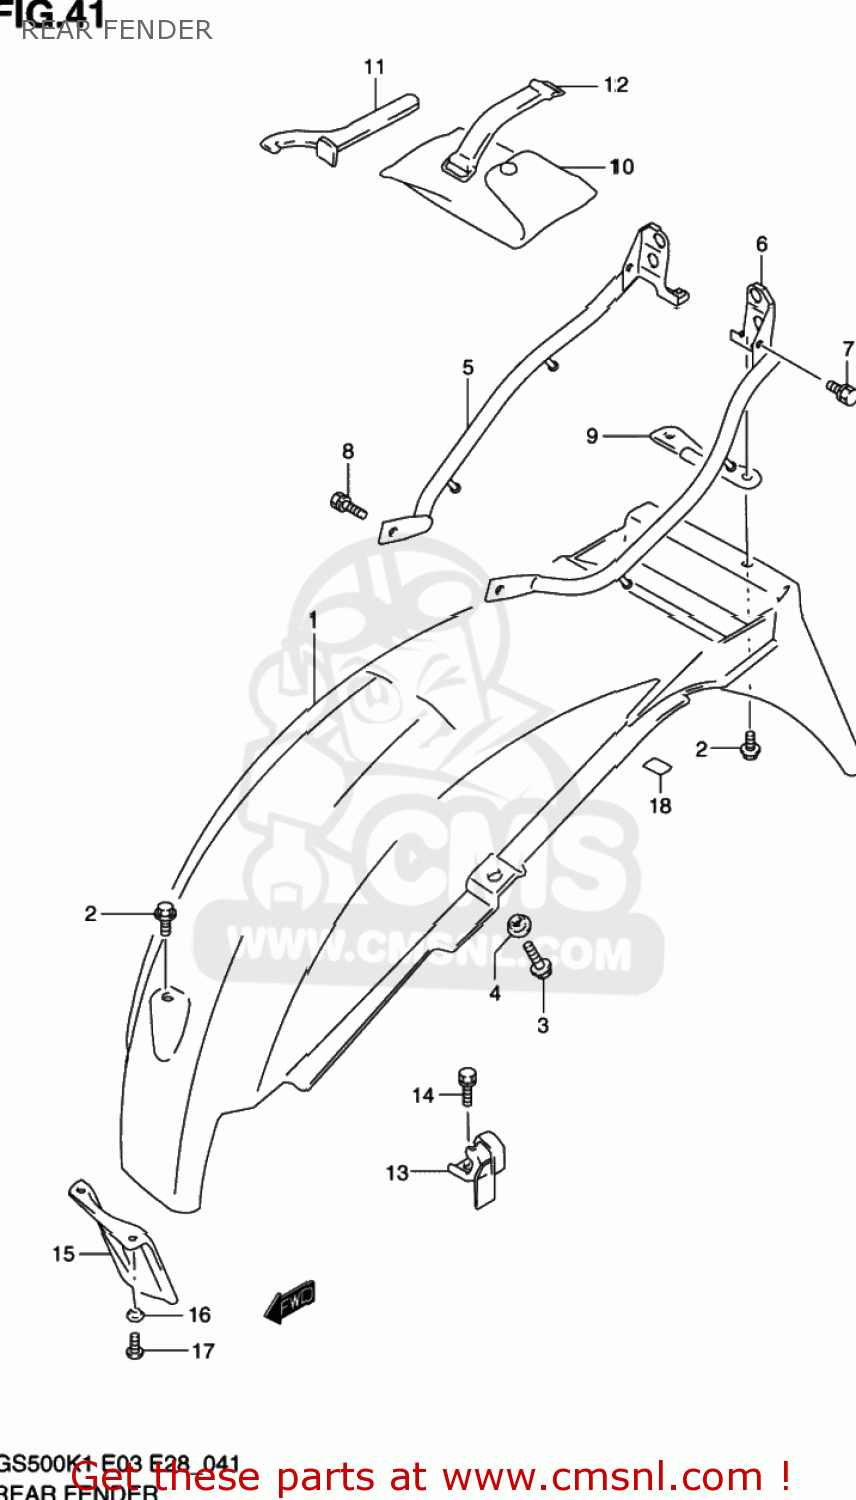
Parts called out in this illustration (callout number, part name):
1	BODY,RR FENDER
2	BOLT(6X16)
3	BOLT
4	WASHER
5	BRACE,RR FENDER,R
6	BRACE,RR FENDER,L
7	BOLT
8	BOLT
9	PLATE,TOOL HOLDER
10	TOOL ASSY
11	CLAMP
12	BAND
13	HOLDER,HELMET
14	BOLT
15	GUARD,RR UNIT MUD
16	WASHER
17	SCREW
18	TAPE,RR FENDER
